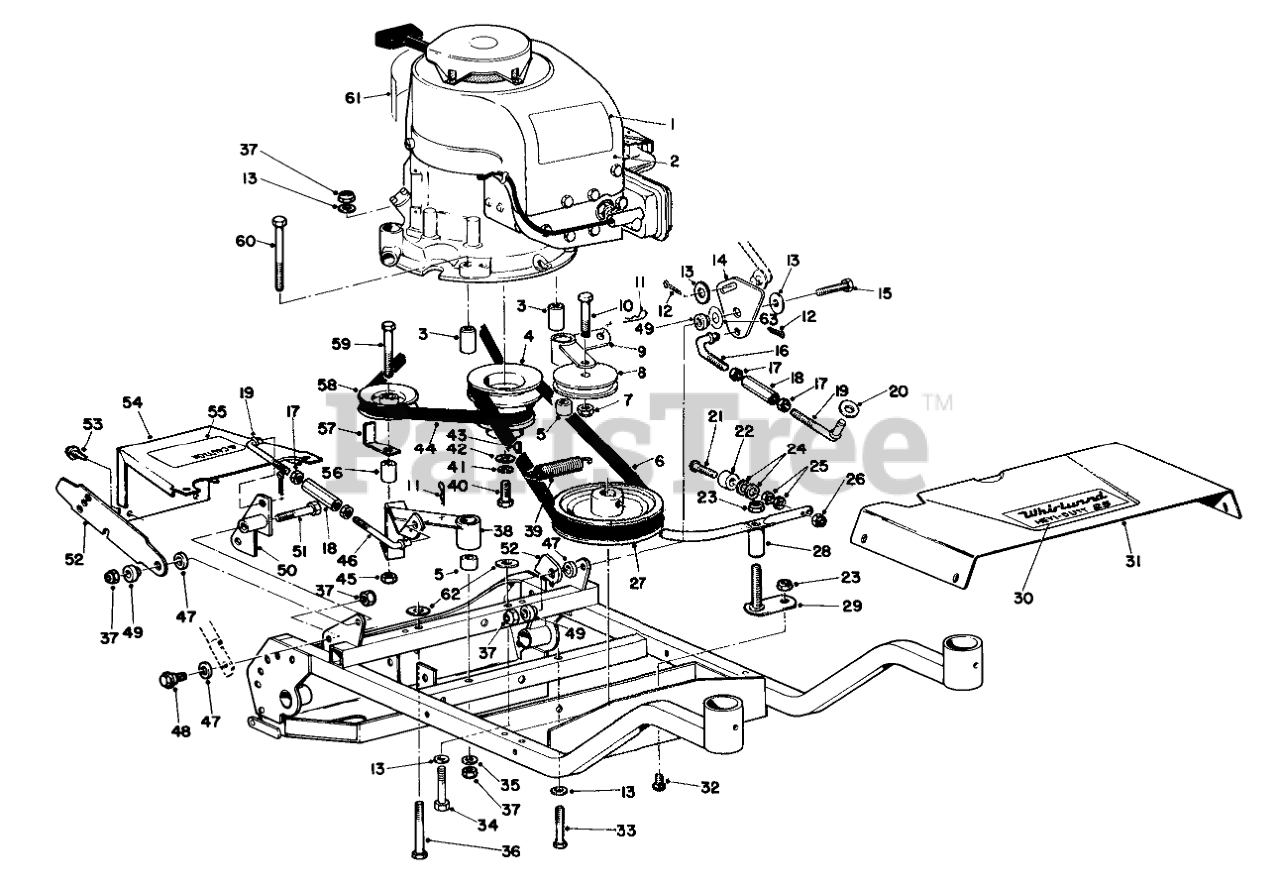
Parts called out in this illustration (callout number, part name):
1	Decal
2	Engine
3	ENGINE PIVOT SPACER
4	ENGINE PULLEY RO
5	BUSHING
7	Nut
8	PULLEY B
9	Arm and Bushing (Incl. Ref. #5)
10	Screw
11	PIN-COTTER
12	PIN-COTTER
13	WASHER-PLAIN
14	CUTTR BELLCRANK WA R
15	5/16-18 X 1-3/4 SCREW
16	CUTTER LINK
17	NUT-KEPS
18	CONTROL ROD SLEEVE
19	LINK CONTROL ROD
20	WASHER
21	10-24X1-1/2 RND HD MS
22	BUMPER
23	NUT-HEX
24	WASHER-FLAT
25	NUT-HEX
26	NUT-LOCK, NI
27	DECK PULLEY R
28	Brake Arm
29	Base Pivot
30	Decal
31	FRONT SHROUD R
32	SCREW-CARR
33	SCREW-HH
34	SCREW-HH
35	WASHER-LOCK/SP
36	SCREW-HH
37	Nut
38	Arm and Bushing (Incl. Ref #5)
39	EXTENSION SPRING
40	SCREW-HH
41	WASHER-LOCK
42	WASHER-FLAT
43	KEY-WOODRUFF
44	V-BELT
45	NUT-HEX
46	Control Rod
47	SPACER
48	SCREW-SHOULDER
49	PIVOT
50	TRACT BELLCRANK WA R
51	SCREW-HH
52	Latch
53	Hex Head Capscrew
54	Rear Shroud
55	DECAL SAF INST
56	SPACER
58	IDLER PULLEY R
59	SCREW-HH
60	SCREW-HH
61	Decal
62	WASHER
63	WASHER
